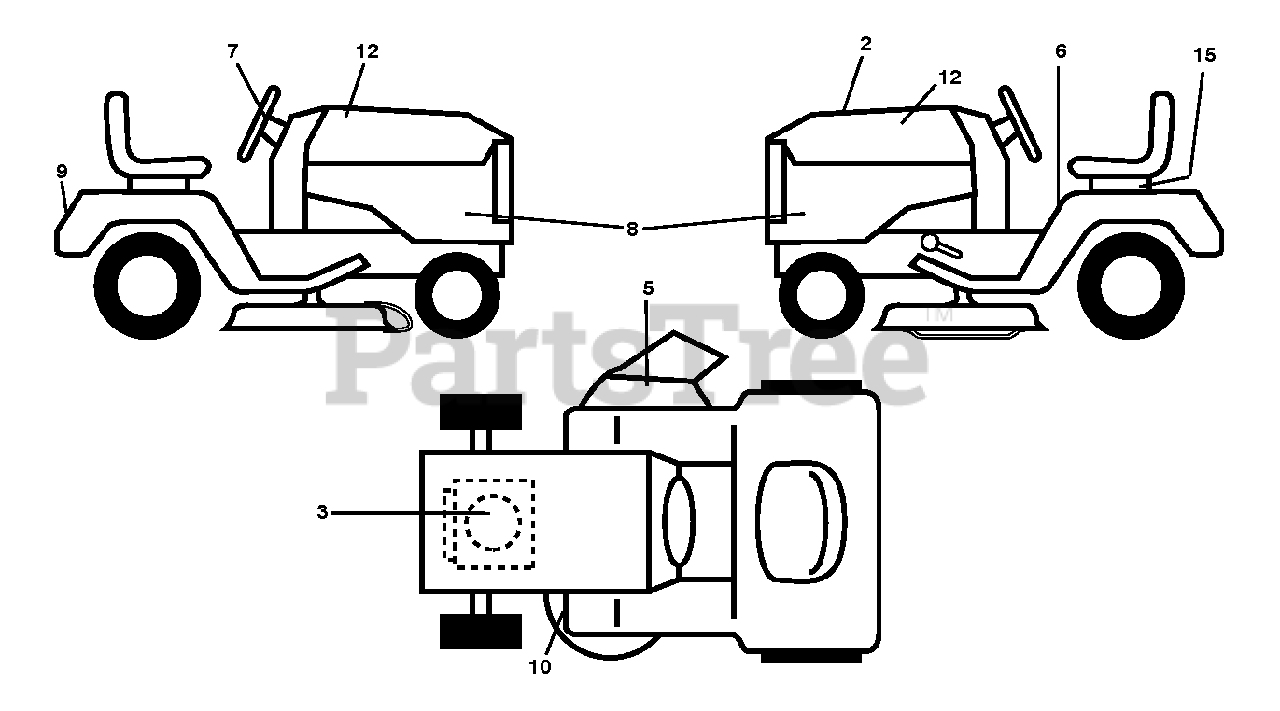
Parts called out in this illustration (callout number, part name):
2	Decal, Replacement BSM31 PB TLW 42C T2
3	DECAL.ENG.BS.15_5PB.DOM.381667
5	DECAL, DECK DEFLECTOR, WARNING
6	DECAL.FENDER.WARNING.ENGLISH
7	Decal, Steering Wheel STDXXSQ PPRO 2015
8	Decal, Side Panel PB185A42 BLK PPRO
9	DECAL.REARFNDR.POULAN PRO.2015
10	DECAL.V-BELT.SCH.42/46"MEC/ELE
12	DECAL.POULAN PRO.2015
15	DECAL BTRY SYMBOLS
